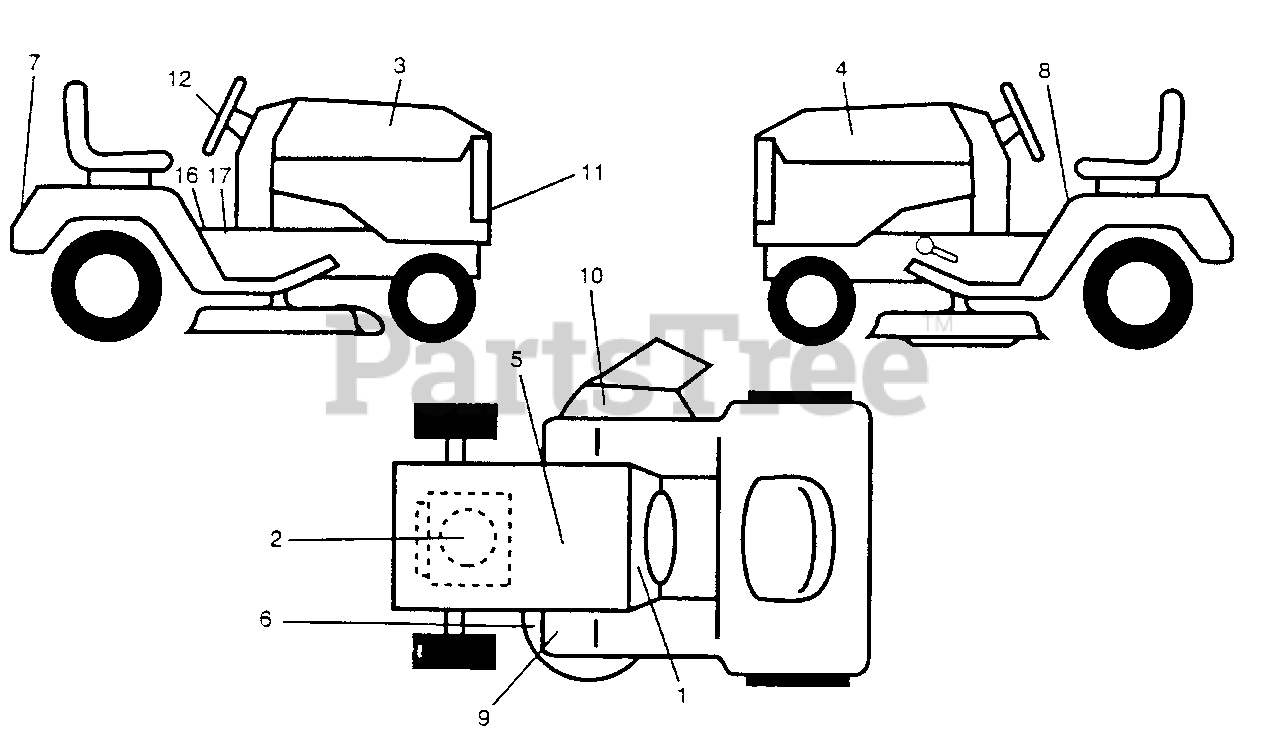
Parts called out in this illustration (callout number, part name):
1	Decal Instruction Dash Eng/fr
2	Decal HP Engine
3	Decal Hood RH
4	Decal Hood LH
5	Decal Caution Battery Fr/ger
6	Decal V-Belt Sch
8	Decal Caution Fender Eng/fr
9	Decal Clutch/brake Eng/fr
10	Decal Warning MULT-LANGUAGE
12	Decal Insert Strg. Whl PP Auto
16	Decal Sdl Cold Start Hyd E/F
17	Decal Brake Parking Saddle
